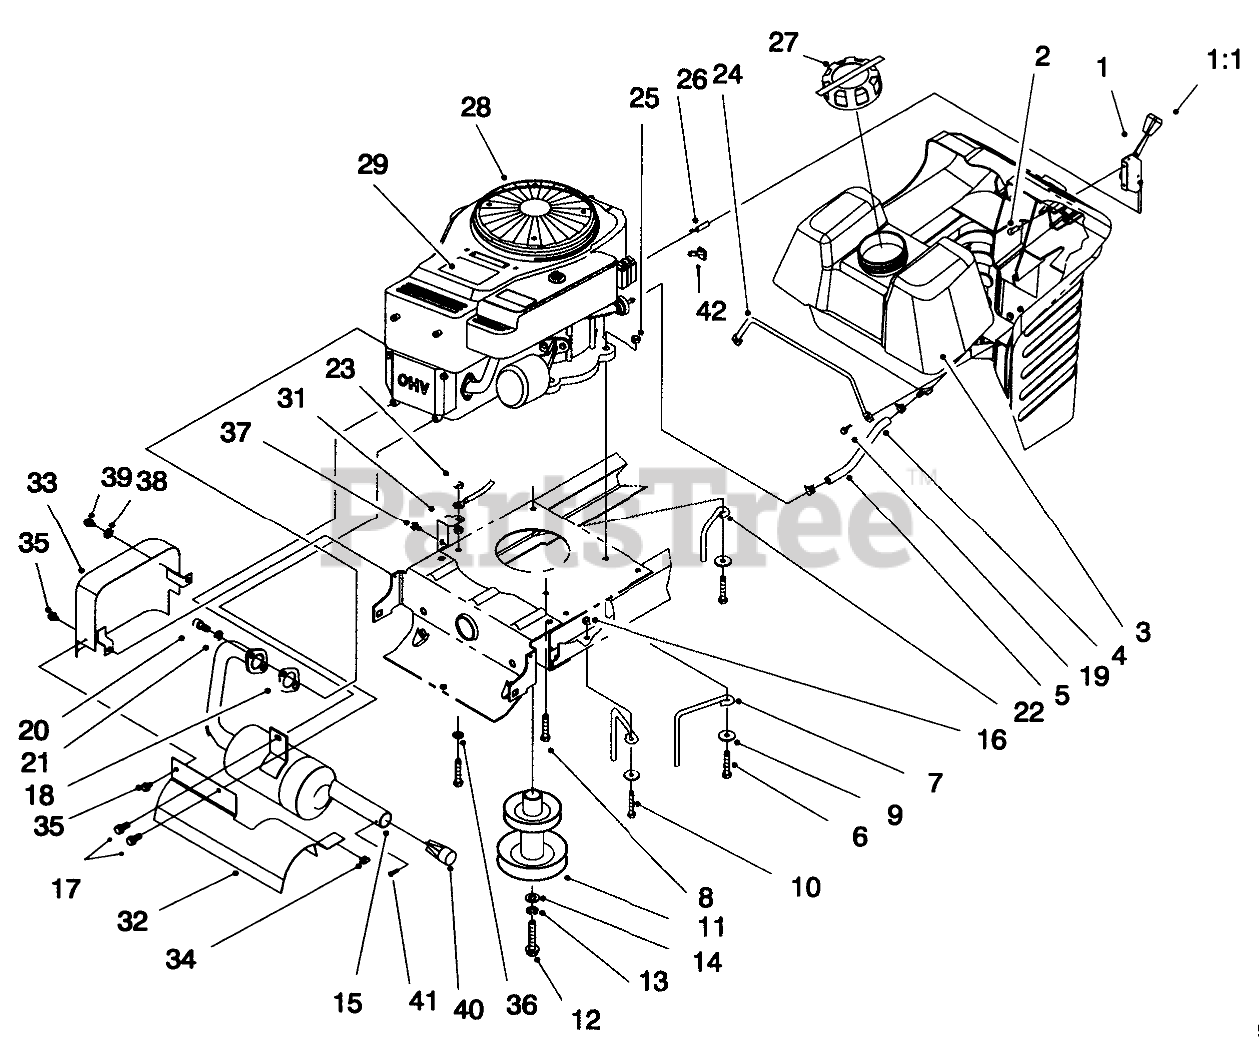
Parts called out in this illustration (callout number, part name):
1	Throttle Control Assembly (Inc. Ref. #1:1)
2	SCREW-SPECIAL
3	GAS TANK ASM
4	HOSE-FUEL
5	CLAMP-HOSE
6	SCREW-HH
7	GUIDE-BELT, ENGINE
8	SCREW-HWH, TAPTITE
9	WASHER-PIVOT
10	SCREW-HH
11	PULLEY, ENGINE
12	SCREW-HH
13	WASHER-LOCK
14	WASHER-FLAT
15	MUFFLER WA 15.5
16	NUT-LOCK, NI
17	SCREW-HWH
18	GASKET-EXHAUST
19	SCREW-SPECIAL
20	SCREW-HSH
21	WASHER-LOCK
22	GUIDE-BELT, RH
23	NUT-KEPS
24	GAS TANK ROD
25	NUT-LOCK, NI
26	THROTTLE CABLE ASM
27	GAS CAP ASM
29	DECAL-ENGINE, 15.5 TORO
31	BRACKET-GROUND
32	Shield-Muffler
33	Shield-Exhaust
34	CLIP-TINNERMAN
35	SCREW-HWHTF
36	WASHER-LOCK
37	SCREW-HWH
38	WASHER-LOCK
39	SCREW-HH
40	SCREEN-SILENCER, EXHAUST
41	SCREW-THD FORM, HWH
42	REDUCER-THROTTLE, RPM
